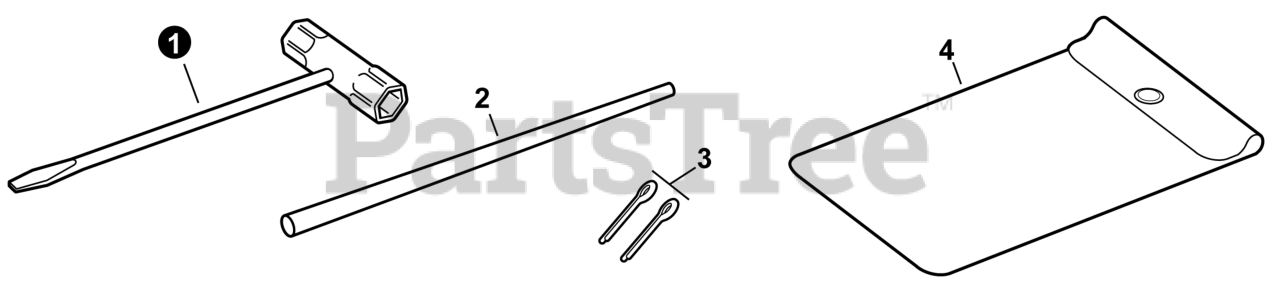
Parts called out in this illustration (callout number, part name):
1	WRENCH, T 17x19 MM
2	TOOL, LOCKING 5x120 MM
3	PIN, COTTER 2x22
4	BAG, TOOL
